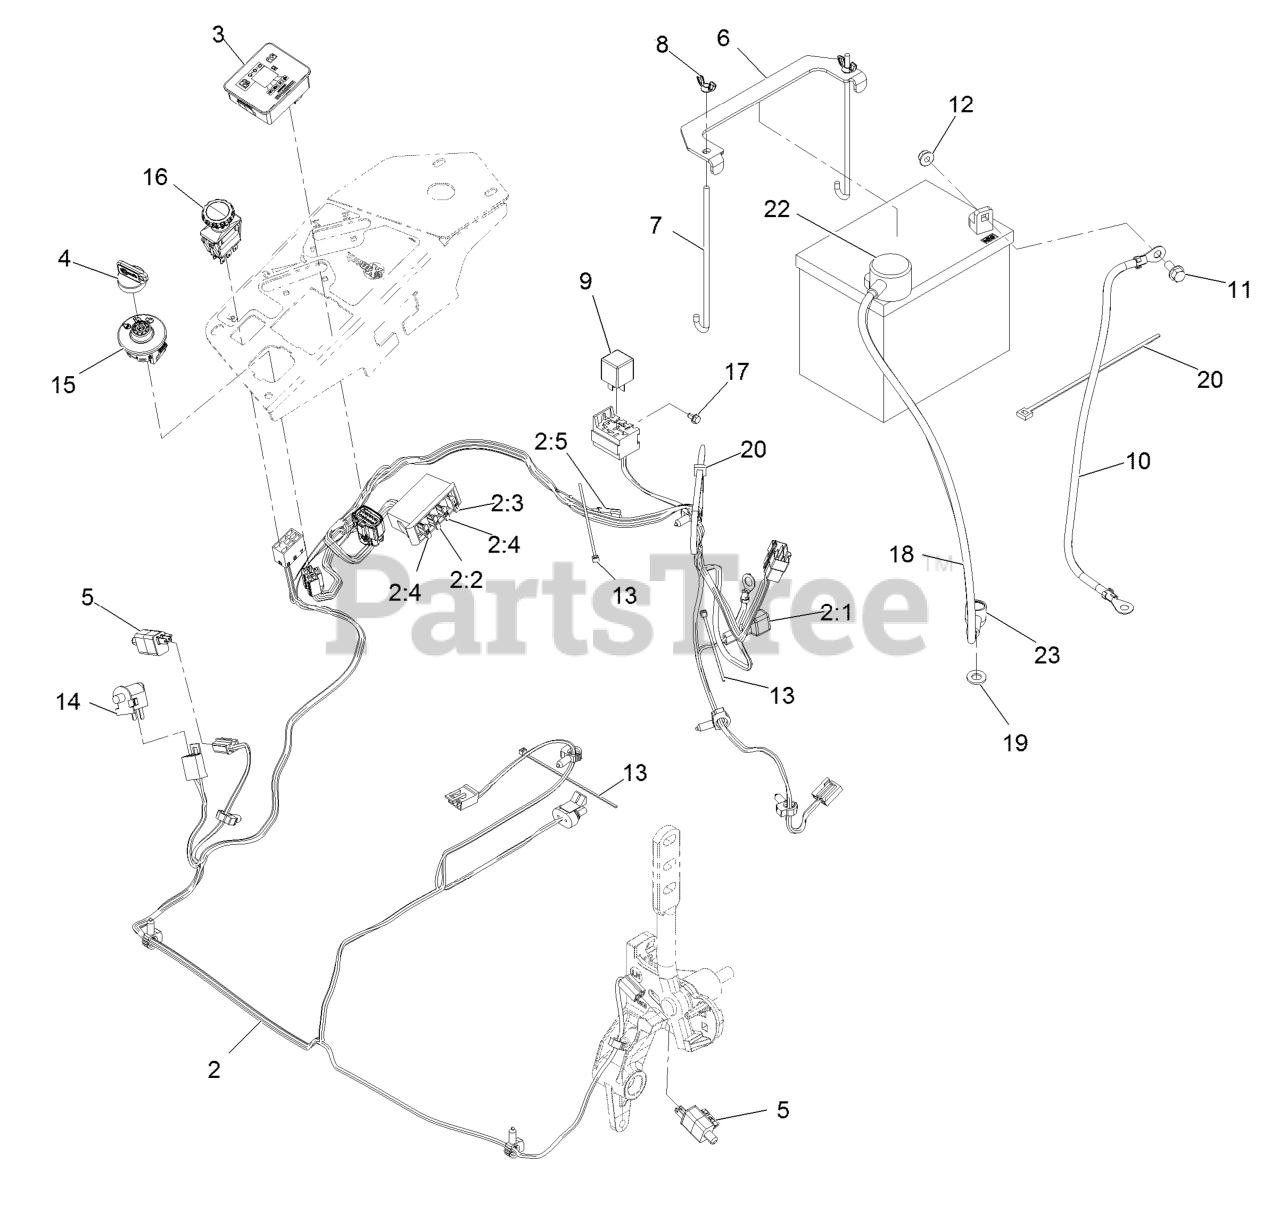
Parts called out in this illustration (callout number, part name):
2	HARNESS-WIRE, MAIN
2:2	FUSE-BLADE, 10 AMP
2:3	FUSE-BLADE, 15 AMP
2:4	FUSE-BLADE, 25 AMP
2:5	CAP-PLUG
3	FUEL/HOUR METER ASM
4	KEYS-IGNITION (SPARE PAIR
4	KEY-IGNITION
6	STRAP-TIE DOWN, BATTERY
7	BOLT-HOLDDOWN
8	WINGNUT
10	CABLE-BATTERY, NEGATIVE
11	SCREW-HHF
12	NUT-HF, NI
13	TIE-CABLE
14	SWITCH-BAIL
16	SWITCH-PTO, 10 AMP
17	SCREW-HWH
18	CABLE-BATTERY, POSITIVE
19	WASHER-FLAT
20	TIE-PLASTIC
22	INSULATOR-BATTERY
23	INSULATOR-SOLENOID
